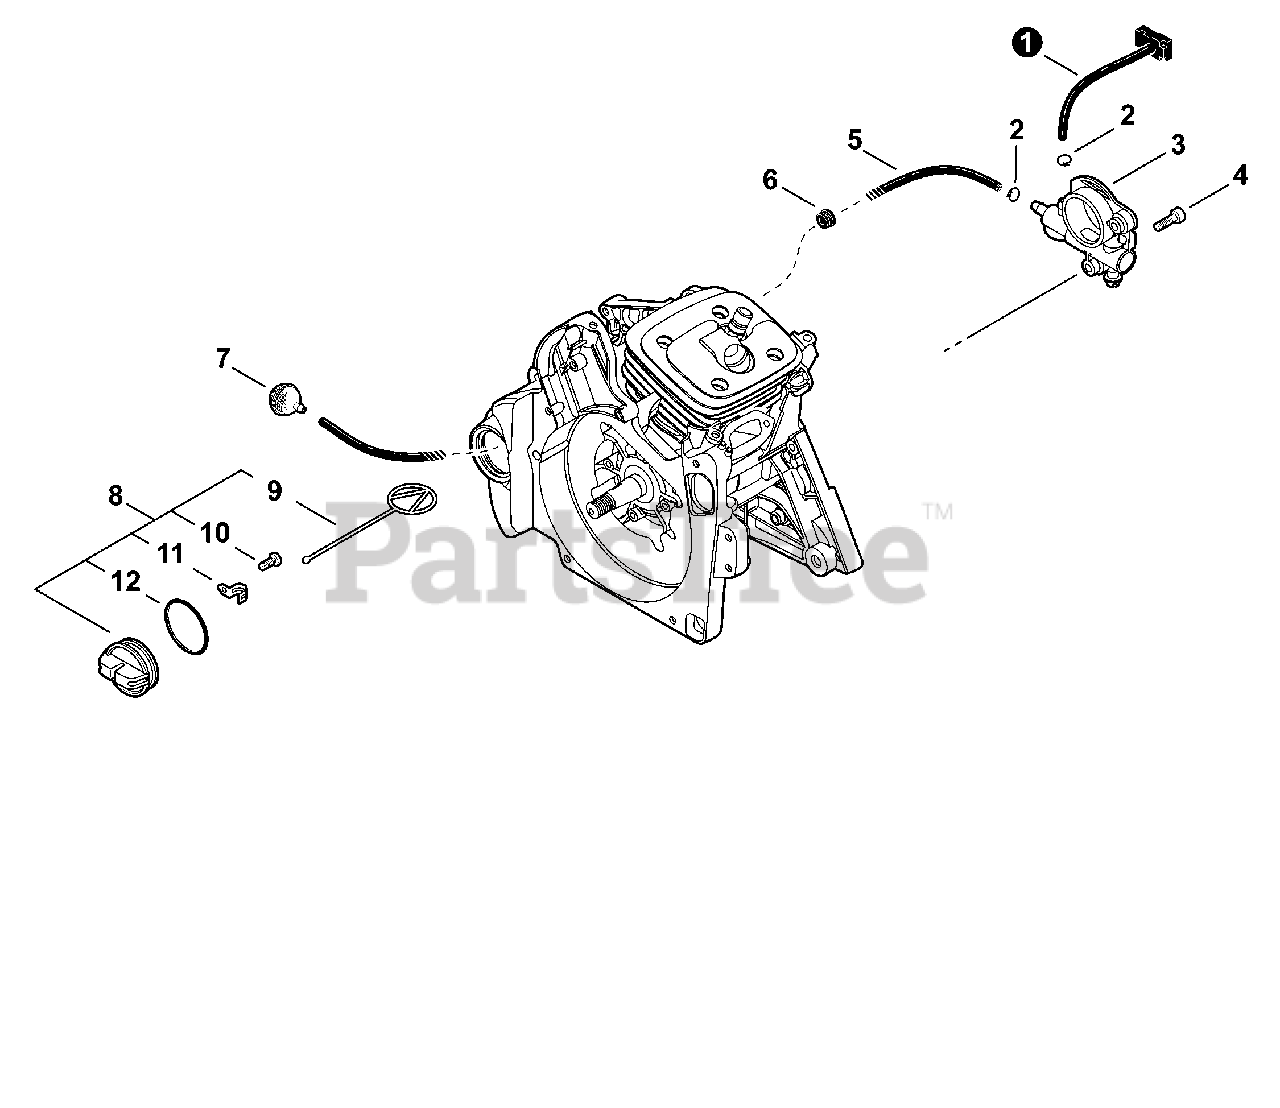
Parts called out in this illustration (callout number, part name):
1	PIPE, OIL
2	CLIP Ø6
3	AUTO-OILER ASSY
4	BOLT, TORX 4×12
5	PIPE, FUEL 3×6×210 BLACK
6	GROMMET
7	FILTER, OIL
8	CAP ASSY, OIL
9	CONNECTOR, CAP L= 60 MM
10	SCREW, TAPPING 3×8
11	RETAINER, CONNECTOR
12	O-RING 28
